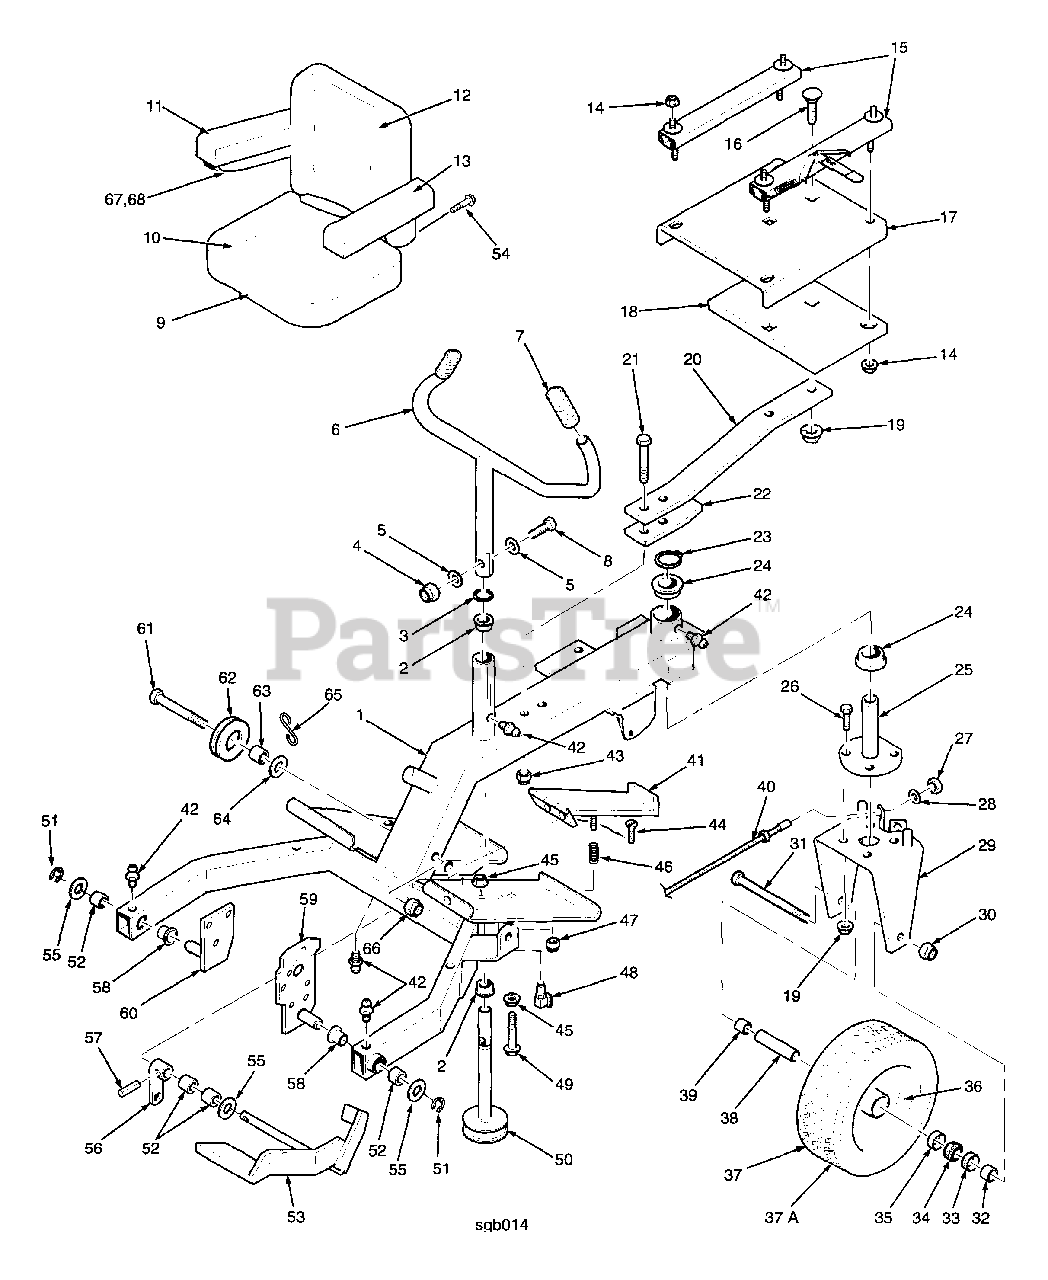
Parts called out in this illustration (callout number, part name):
1	Steering Frame
2	Bronze Bushing, 7/8 ID x 1.0 Flanged
3	Retaining Ring, 7/8 external
4	Hex Nut, Elastic Stop 5/16-18
5	Flat Washer, 5/16 (3/8 x 7/8 x 13 ga.)
6	Steering Handle
7	Grip
8	Bolt, Hex Hd., 5/16-18 x 1-3/4"
9	Seat Assy.
10	Cushion Assembly
11	Arm Pad - R H.
12	Seat Sack Cushion
13	Arm Pad - L.H.
14	Serr. Fl. HH. Nut, 5/1 6-18
15	Seat Adjuster Track
16	Bolt, RDHD Carr. 3/8-16 x 1-1/2 (52" & 61")
17	Seat Plate
18	Ballast, Seat Mount (72" cutter deck only)
19	Serr Fl. Hex Nut, 3/8-16
20	Seat Spring
21	Bolt, Hex Hd., 7-16-14 x 3-1/2"
22	Reinforcement, Seat Spring
23	Retaining Ring, 1-1/8" external
24	Bushing, Oilite - 1-1/8 ID x 1.0 Flanged
25	Rear Wheel Pivot
26	Bolt, Hex Hd., 3/8-16 x 1-1/4"
28	Lock Washer, 3/8 Internal Tooth
29	Rear Wheel Yoke
30	Hex Elastic Stop Nut, 5/8-11
31	Bolt, Hex Hd. 5/8-11 x 9"
32	Spacer, Rear Wheel, short
33	Seal, Grease
34	Bearing Cone
35	Bearing Cup
36	Rim Only
37	Rear Wheel Assy
37A	Tire Only
38	Sleeve, Rear Wheel
39	Spacer, Rear Wheel
40	Cable, Steering
41	Pedal, Foot Safety Switch
42	Grease Fitting
43	Hex Elastic Stop Nut, 7/16-14
44	Screw, Phillips flat hd #10-32 x 3/4"
45	Serr. Fl. Hex Nut, 1/4-20
46	Spring, Foot Safety Switch
47	Hex Nut, Elastic Stop Lock, 1/4-20
48	Switch, Foot Safety
49	Bolt, Hex Hd, 1/4-20 x 1-3/4"
50	Steering Shaft
51	Retaining Ring 3/4 Ext "E"
52	Bushing, oil lube - 3/4 ID x 1.0
53	Foot Pedal
54	Screw w/washer, 1/4-20 x 75"
55	Flat Washer, 3/4 x 1-1/4 x 16 Ga.
56	Foot Pedal Arm
57	Pin, Drive Lock 3/16 x 1-1/4"
58	Bushing, oil lube - 3/4 x .50 Flanged
59	Sulky Mtg. Brkt L.H.
60	Sulky Mtg. Brkt R.H.
61	Bolt, Hex Hd, 1/2-13 x 5-1/2"
62	Pulley, Winch Cable
63	Bushing, oil lube - 1/2 ID x 56
64	Flat Washer, 1/2 (.562 x 1.375 x .109)
65	Retainer, Winch Cable
66	Hex Elastic Stop Nut, 1/2-13
67	Arm Rest Bracket, Left Hand
68	Arm Rest Bracket, Right Hand
